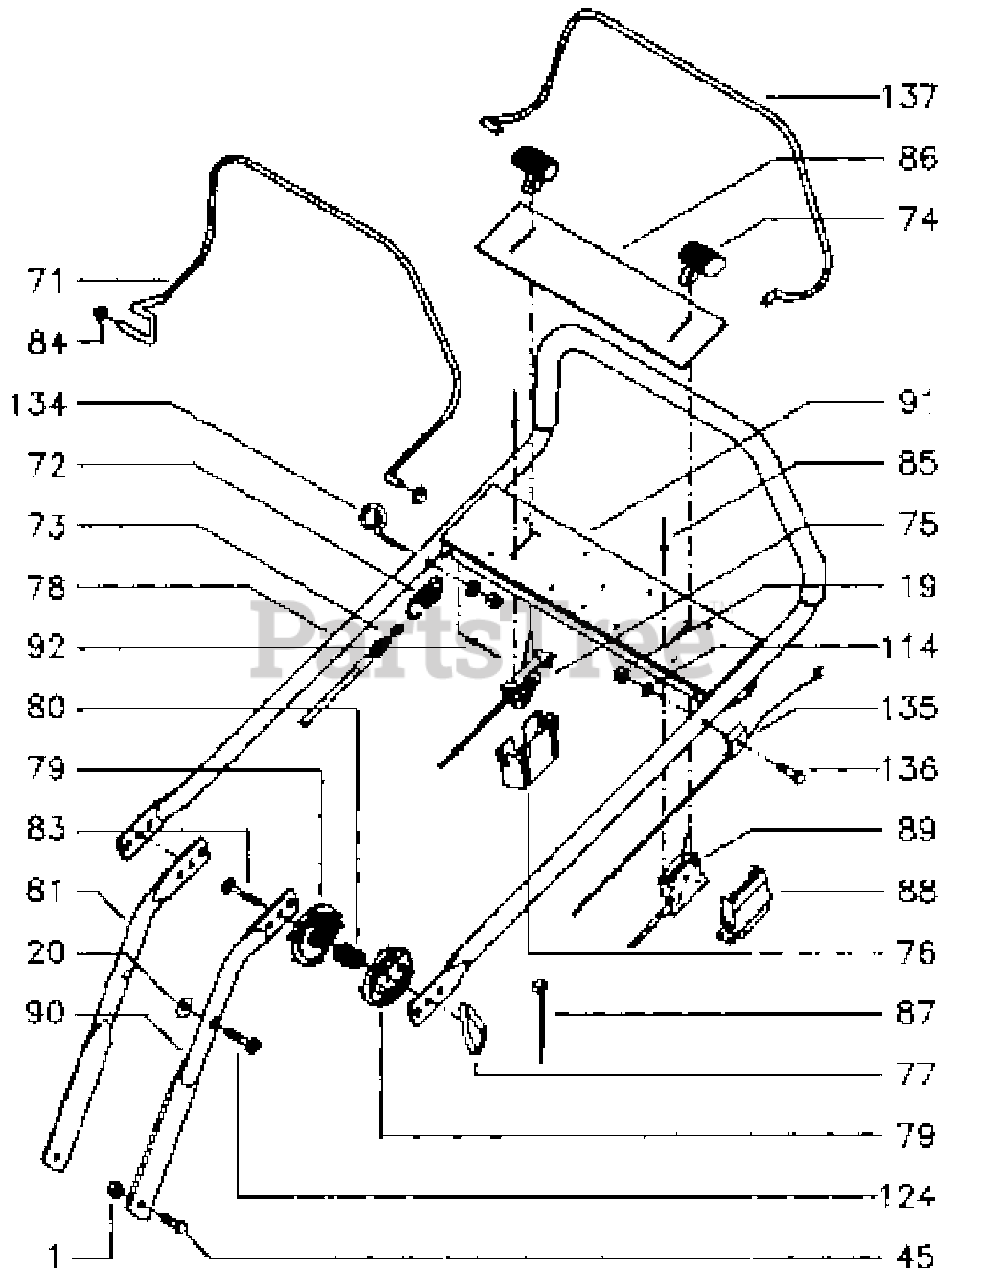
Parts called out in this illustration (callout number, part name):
1	Locknut M8
19	Locknut M6
45	Screw M6s 8x25
74	Knob
75	Control Wire
77	Wingnut
89	Control
90	Handle
92	Rivet
134	Cable Guide
136	Bolt Flange
